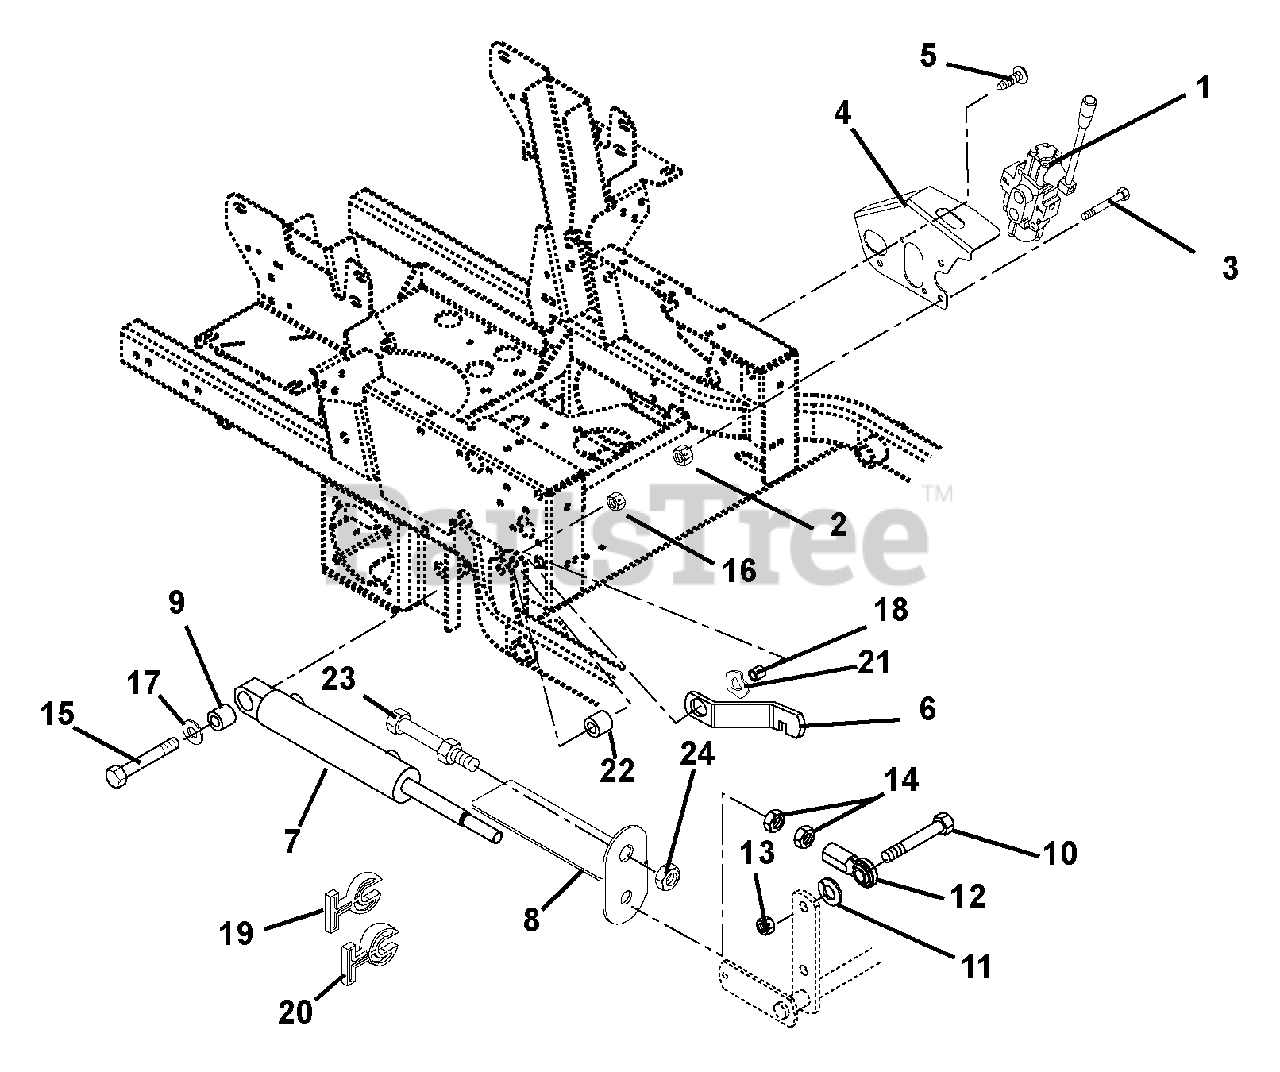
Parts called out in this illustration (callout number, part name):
1	VALVE, HYDRAULIC
2	@NUT-LK-TOP-FLG .31-18 YWZC
3	@BLT-HEX .31-18X2.50 GR5 YWZC
4	BRKT, VALVE MOUNTING
5	@SCR-TAP .38-16X.50 HWH TR YWZ
7	CYLINDER, LIFT
8	CUT INDICATOR/GUARD - BLACK
9	BUSHING, .516X1.000X1.050 LG
10	BLT-HEX .62-11X2.25 YWZC GR8
11	@WSHR-LK .62X.156 REG YWZC
12	ROD END, 5/8 RH - FEMALE
13	@NUT-LK-CTR .62-11 YWZC
14	NUT-JAM .625-18 YWZC
15	@BLT-HEX .50-13X3.50 GR5 YWZC
16	@NUT-LK-TOP-FLG .50-13 YWZC
17	WSHR-FL-STL .515X1.625X.250 YZ
18	BSHG-FLG .515X.750X.285X1.120
19	STOP, CYLINDER .34 THK
20	STOP, CYLINDER .680 THK
21	WASHER-WAVE .760X1.120X.080
22	SPACER .516X1.000X.875
24	NUT-JAM .75-16 YWZC
